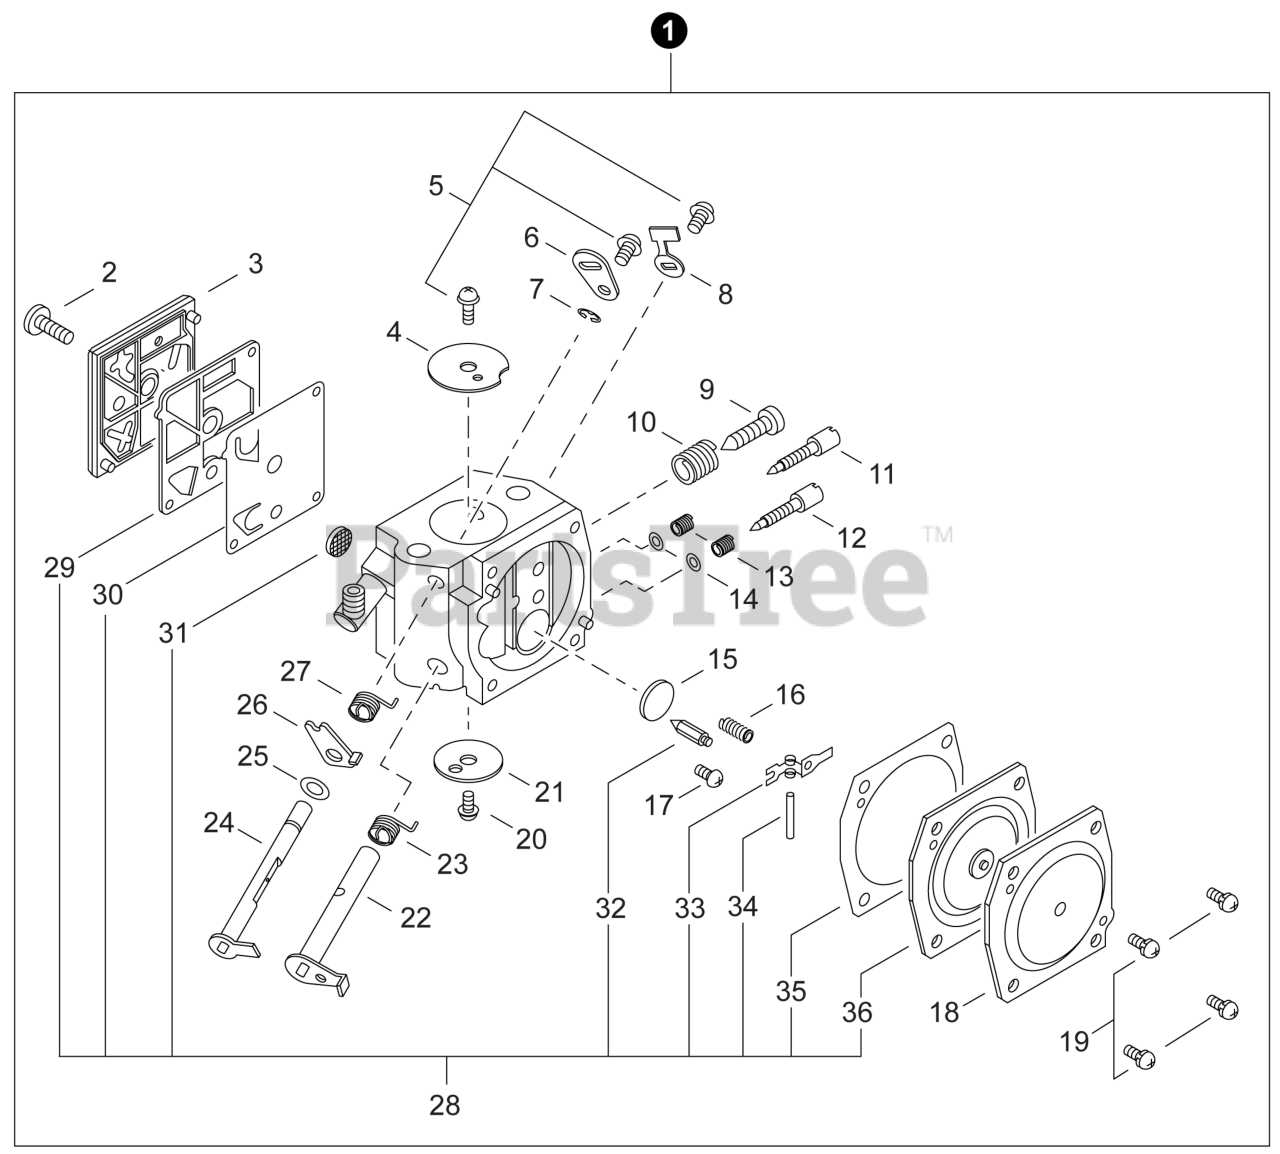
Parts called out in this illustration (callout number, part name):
1	CARBURETOR - HDA-337
3	COVER, FUEL PUMP
4	VALVE, THROTTLE
6	LEVER, CHOKE
8	STOP, THROTTLE
9	SCREW, IDLE ADJUST
10	SPRING, IDLE ADJUST
13	SPRING, NEEDLE
14	WASHER
15	PLUG, WELCH
18	COVER, METERING DIAPHRAGM
21	VALVE, THROTTLE
22	SHAFT, THROTTLE
23	SPRING, THROTTLE RETURN
24	SHAFT, CHOKE
26	LEVER, FAST IDLE
27	SPRING, CHOKE RETURN
28	REPAIR KIT
29	GASKET, FUEL PUMP
30	DIAPHRAGM, FUEL PUMP
31	SCREEN, FUEL INLET
32	VALVE, INLET NEEDLE
33	LEVER, METERING
34	PIN, METERING LEVER
35	GASKET, METERING DIAPHRAGM
36	DIAPHRAGM, METERING
